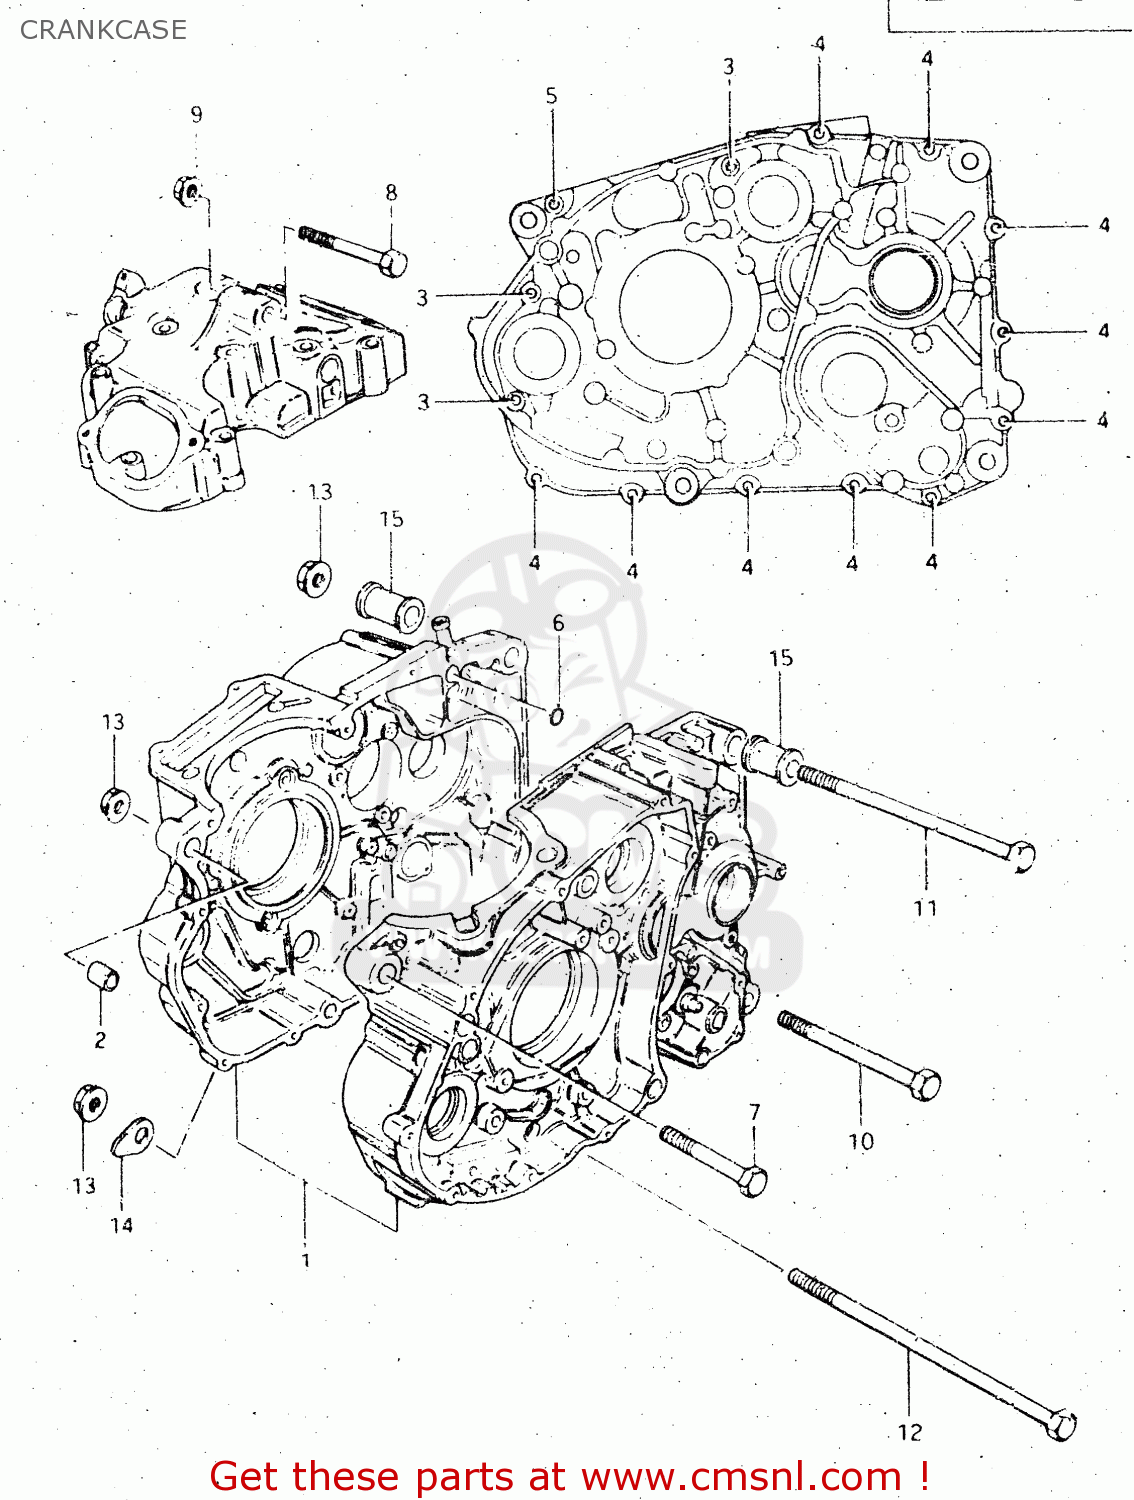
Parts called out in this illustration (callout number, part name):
1	CRANKCASE ASSEMBLY
2	PIN
3	BOLT (6X60)
4	BOLT 6X40
5	BOLT 6X30
6	O-RING
7	BOLT 10X70
8	BOLT, UPPER
9	NUT
10	BOLT(10X120)
11	BOLT(10X180)
12	BOLT
13	NUT 10MM
14	WASHER
15	SPACER,ENGINE MOUNT
